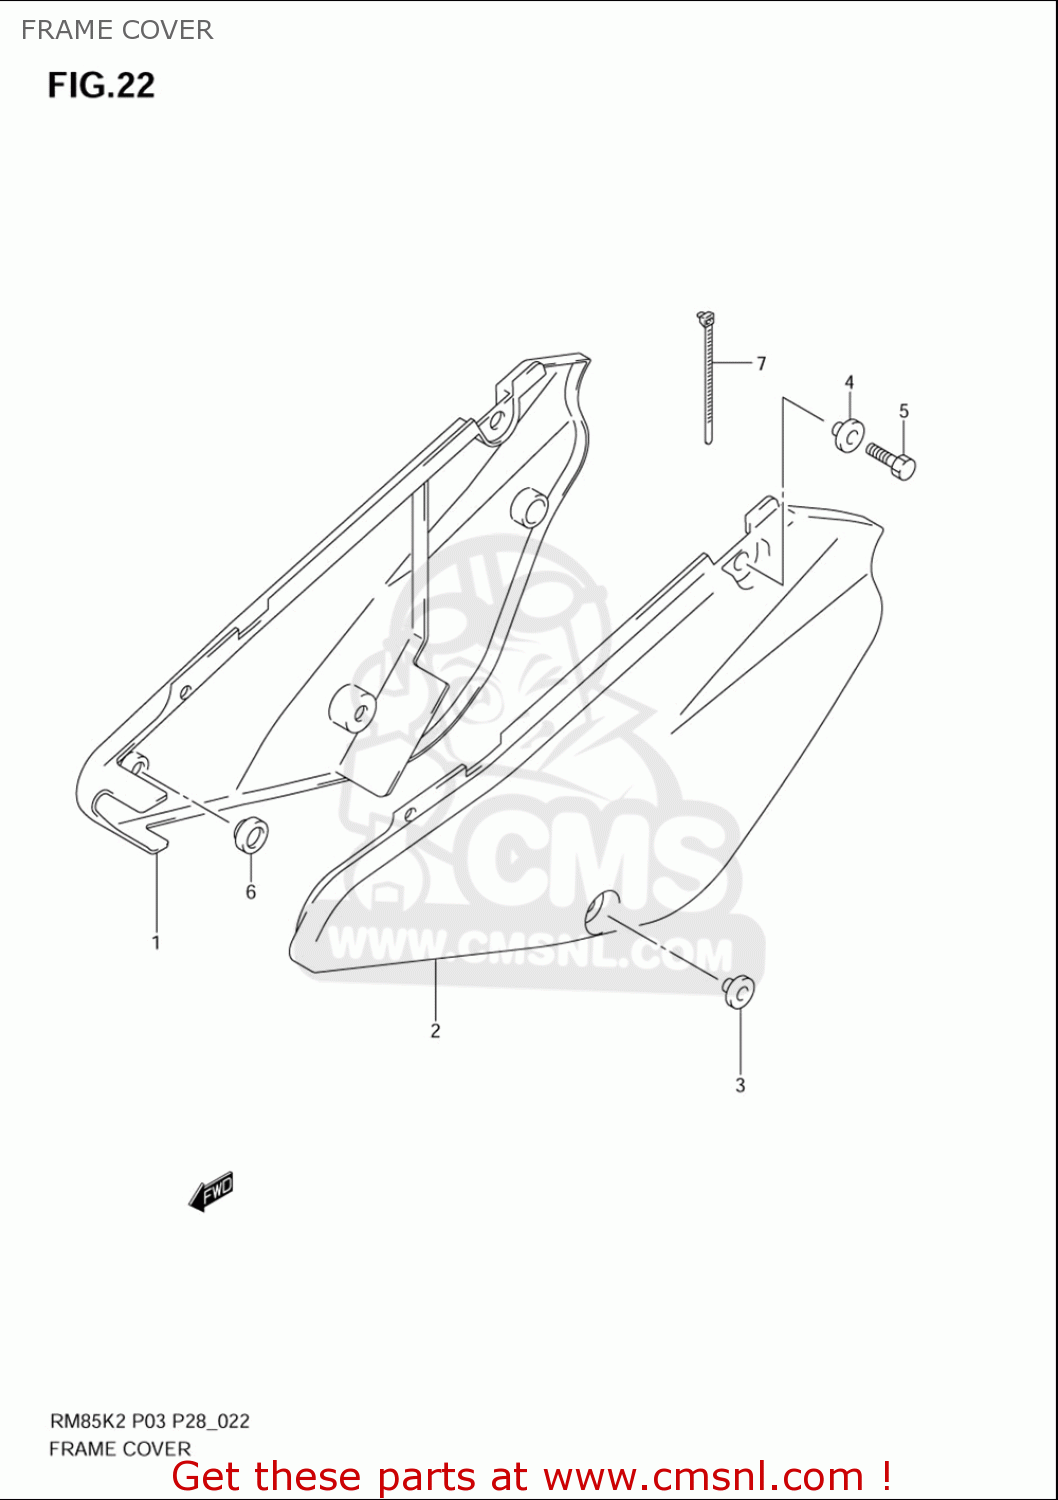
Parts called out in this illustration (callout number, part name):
1	COVER,SIDE,R(WHITE)
2	COVER,SIDE,L(WHITE)
3	WASHER
4	WASHER(6.5X20X1.6)
5	BOLT(6X16)
6	CUSHION
7	CLAMP(L:150)
